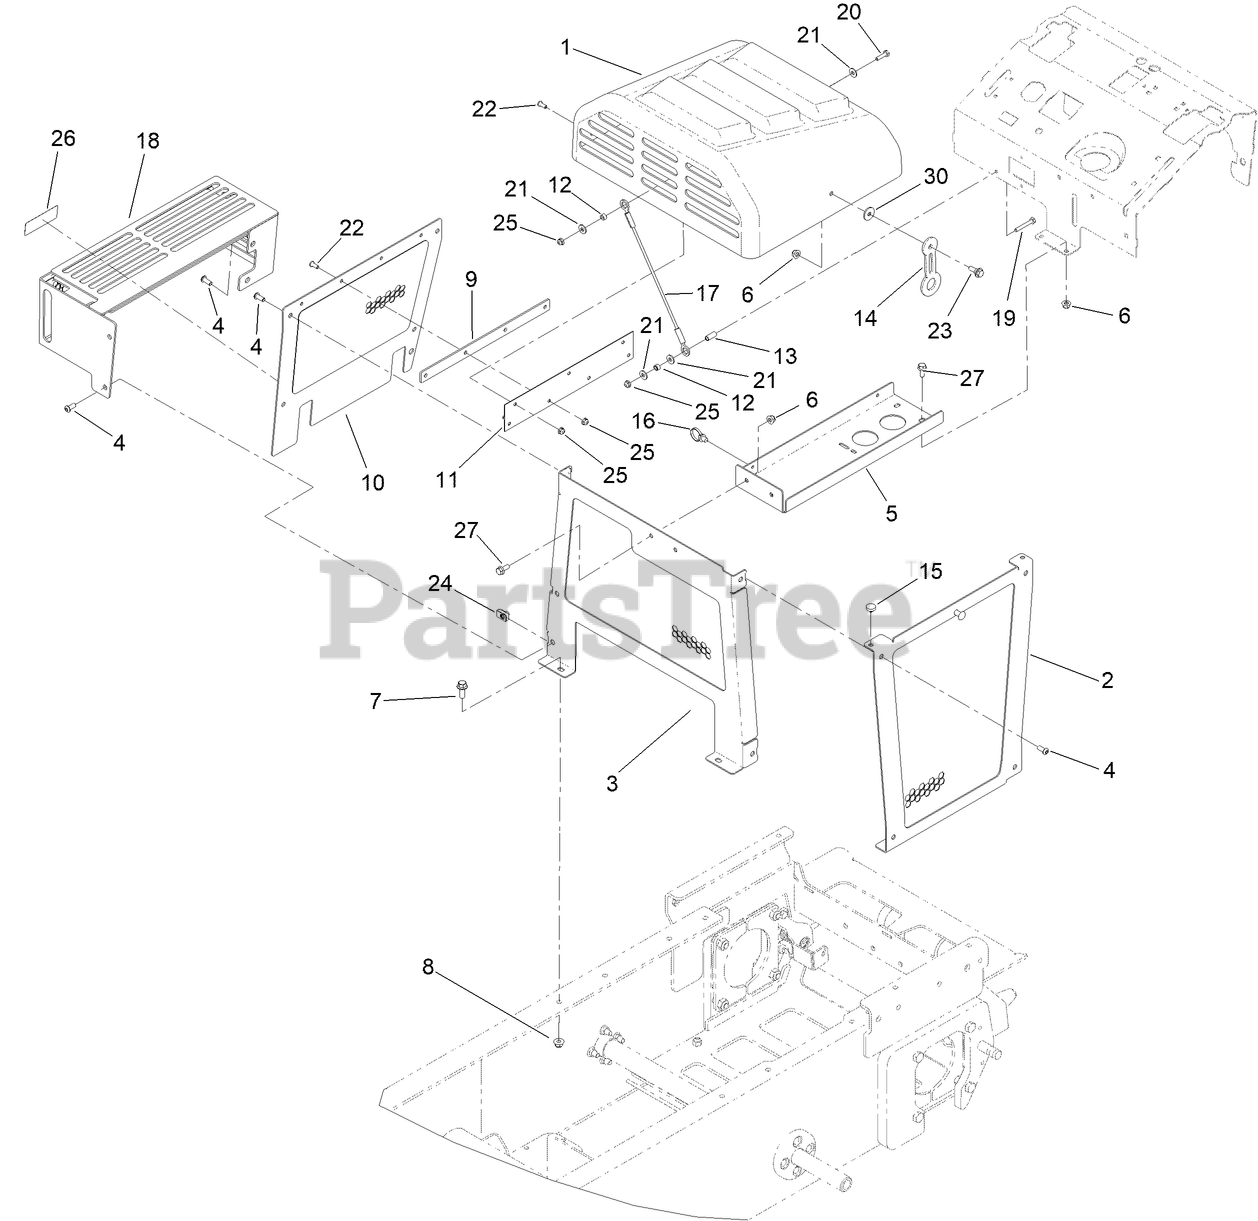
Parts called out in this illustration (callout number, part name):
1	HOOD ASM
2	PANEL-SIDE, LH
3	PANEL-FRONT (WELDED)
4	SCREW-HSBH
5	PLATFORM-BATTERY
6	NUT-HF, NI
7	SCREW-HHF
8	NUT-HF, NI
9	PLATE-SPACER, HOOD
10	PANEL-SIDE, UPPER
11	HINGE-HOOD
12	SPACER-BLADE, ROTOR
13	SPACER-BRAKE, PARKING
14	LATCH-RUBBER
15	BUMPER
16	CLIP-TIE
17	LANYARD
18	GUARD-MUFFLER
19	SCREW-HH
20	SCREW-HH
21	WASHER-FLAT
22	SCREW-HWH
23	SCREW-SHOULDER
24	NUT-CLIP, U
25	NUT-HF
26	DECAL-ARRESTOR, SPARK
27	SCREW-HHF
30	WASHER-FLAT
